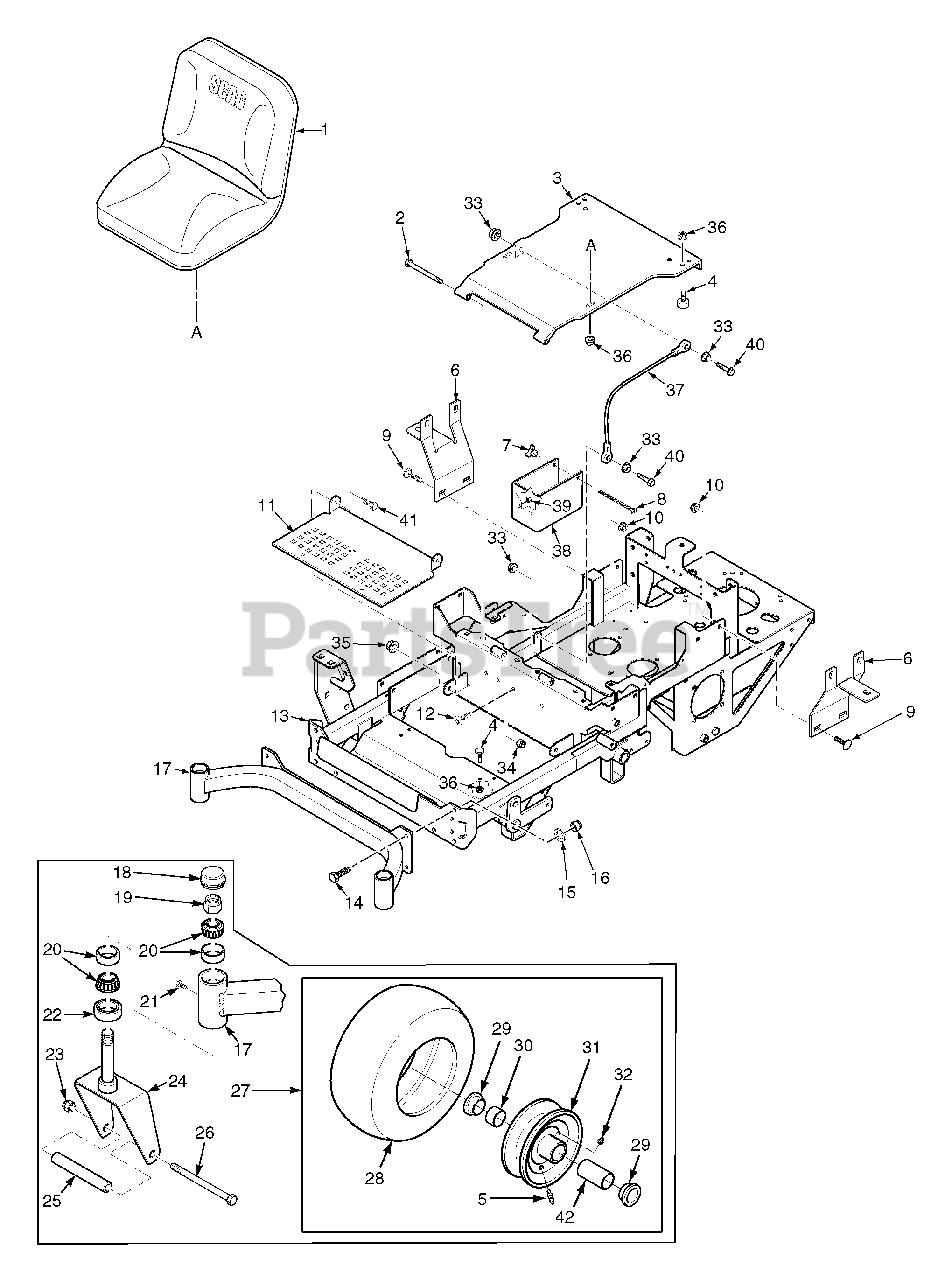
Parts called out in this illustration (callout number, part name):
1	Seat Assembly
2	Bolt, Hex Head 3/8-16 x 3-3/4"
3	Seat Mounting Base Weldment
4	Bumper, Rubber
5	Tire Valve
6	Bracket, Fuel Tank Mounting
7	Wing Nut, 1/4-20
8	Bolt, Carriage 1/4-20 x 6"
9	Bolt, Carriage 5/16-18 x 3/4"
10	Nut, Serr. Flange 5/16-18
11	Foot Plate
12	Bolt, Torx 3/8-16 x 1"
13	Mainframe Weldment
14	Bolt, Hex Head 7/16-14 x 1-1/4"
15	Lockwasher, 7/16"
16	Nut, Elastic Stop 7/16-14
17	Caster Support Weldment - 36"
18	Cap, Grease
19	Nut, Elastic Stop 1"-14 Jam
20	Bearing w/Race
21	Plug, 1/4-28 Self Tap
22	Seal, 2" O.D. x 1.625 I.D.
23	Nut, Elastic Stop 1/2-13
24	Caster Yoke Weldment
25	Sleeve, Caster Wheel
26	Bolt, Hex Head 1/2-13 x 6-1/2"
27	Caster Wheel Assy.
28	Tire, 11" x 4"-5
29	Retainer, .625 x 1.375
30	Roller Bearing, .625 x 1"
31	Wheel, 5" x 3.25"
32	Grease Fitting, 1/4-28 Straight
33	Nut, Serr. Flange 1/4-20
34	Nut, Elastic Stop 5/16-18
35	Nut, Elastic Stop 3/8-16
36	Nut, Serr. Flange 5/16-18
37	Cable, Seat Stop
38	Battery Box
39	Nut, Serr. Flange 3/8-16
40	Bolt, Hex Head 1/4-20 x 1-1/4"
41	Bolt, Hex Head 3/8-16 x 1"
42	Roller Bearing, .625 x 3-1/4"
